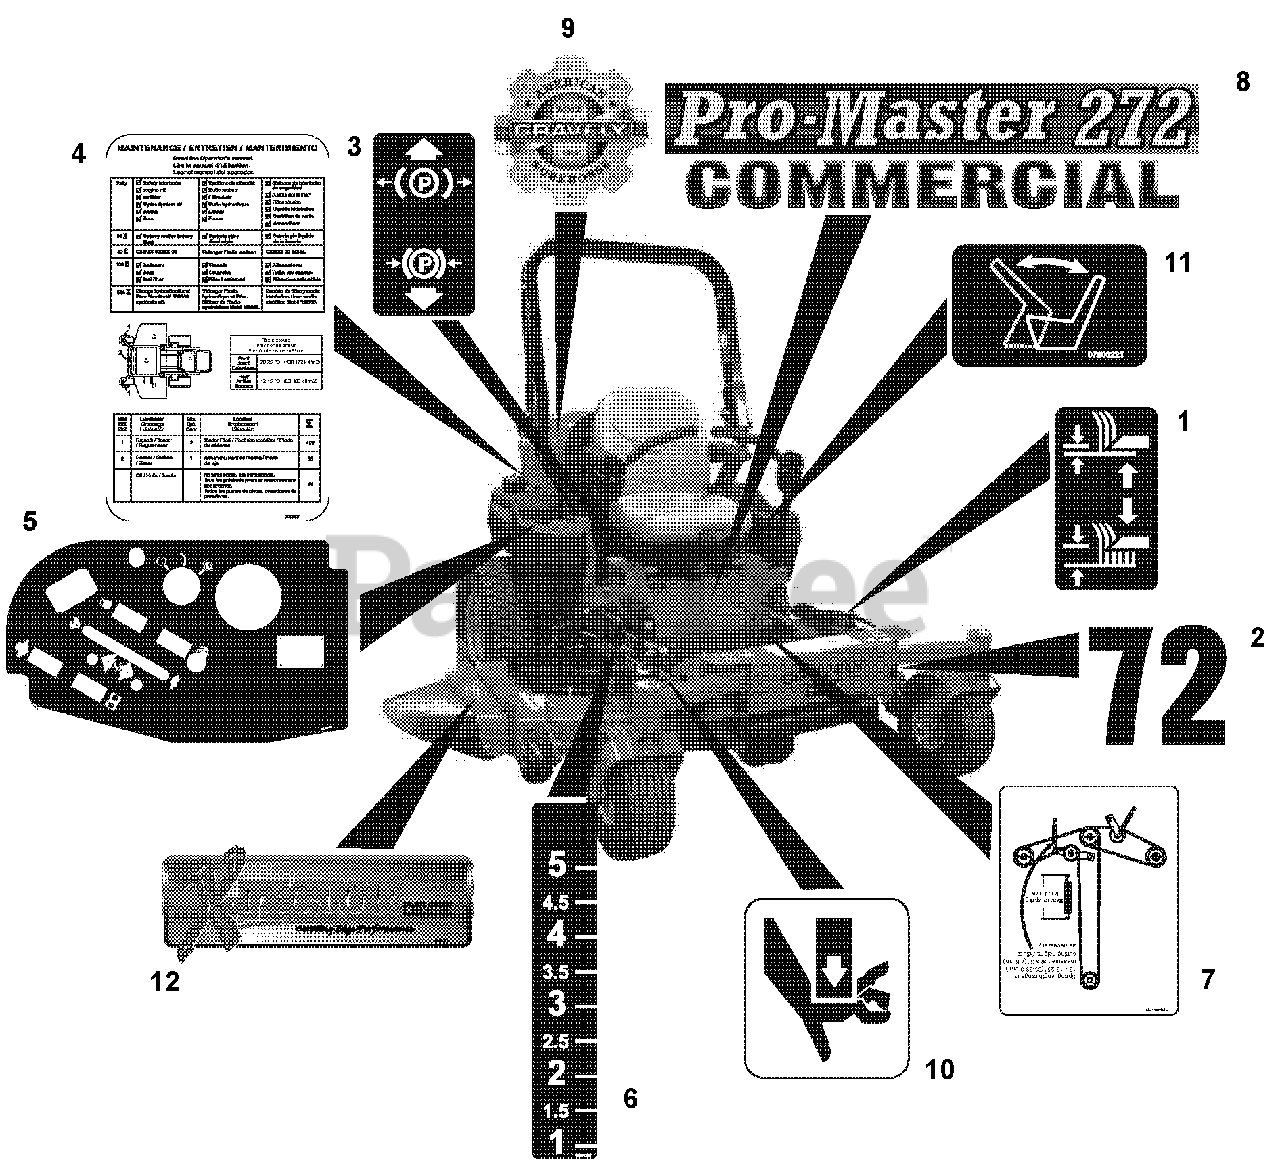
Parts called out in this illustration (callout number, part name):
1	DECAL- LIFT LEVER
2	DECAL, 60"
3	DECAL, PARKING BRAKE LEVER
4	DECAL-MAINTENANCE INSTRUCTIONS
5	DECAL-CONTROL PANEL - DIESEL
6	DECAL, HEIGHT OF CUT
7	DECAL, BELT ROUTING
8	DECAL, PROMASTER 260
9	DECAL, GRAVELY HERITAGE-LARGE
10	DECAL, PINCH POINT
11	DECAL - SEAT RELEASE
12	DECAL-X-FACTOR DECK
